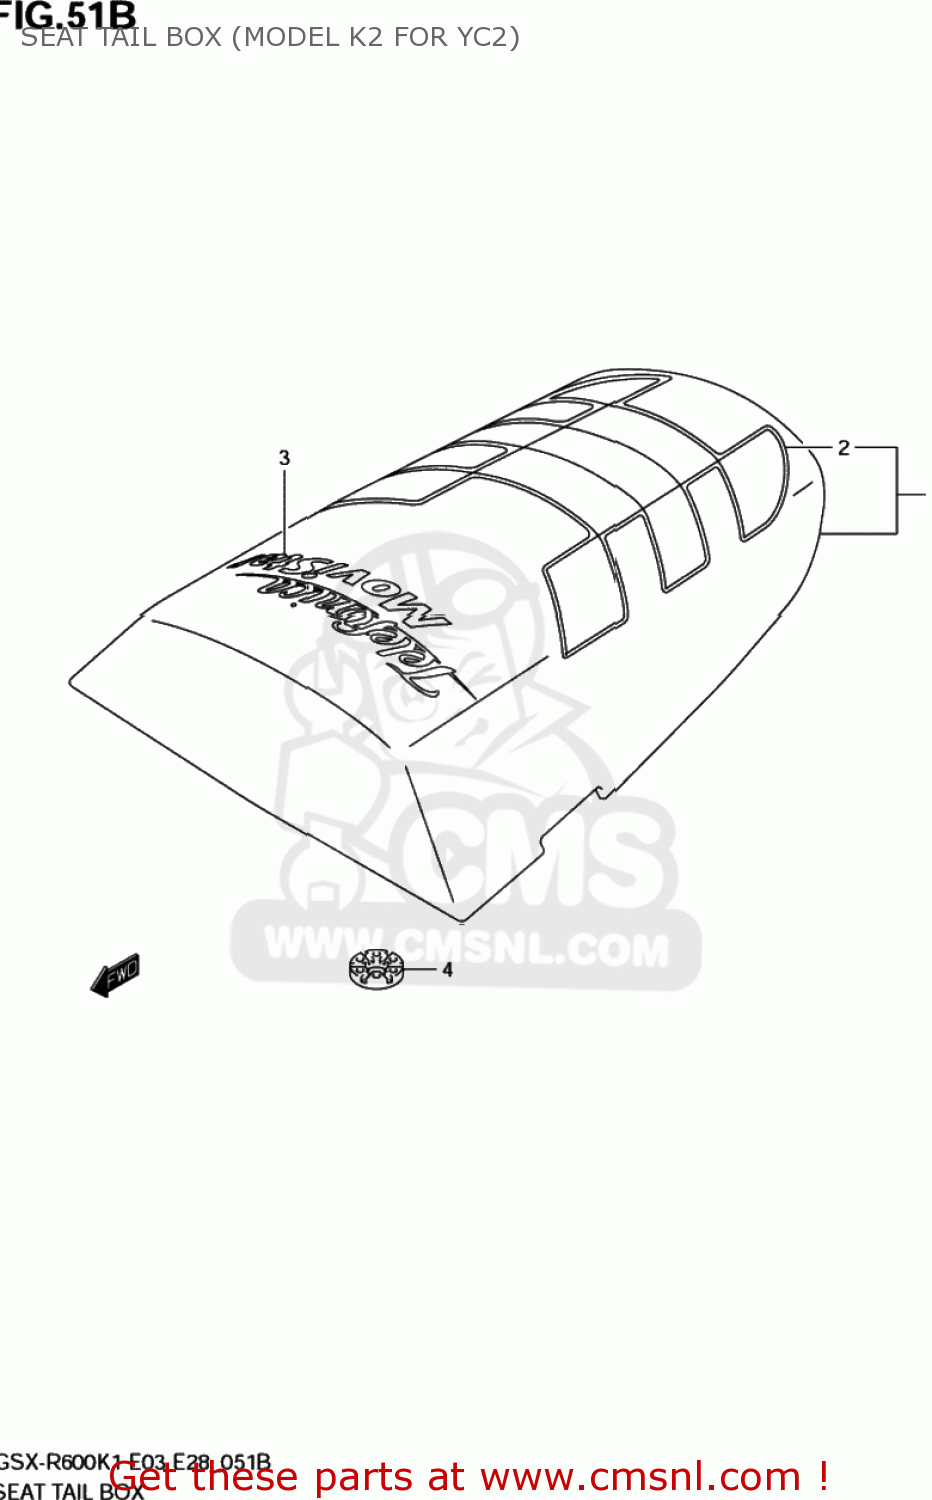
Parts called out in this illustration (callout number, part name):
1	BOX ASSY,SEAT TAIL(BLUE)
2	TAPE,BOX SEAT TAIL
3	EMBLEM,MOVISTAR
4	CUSHION
